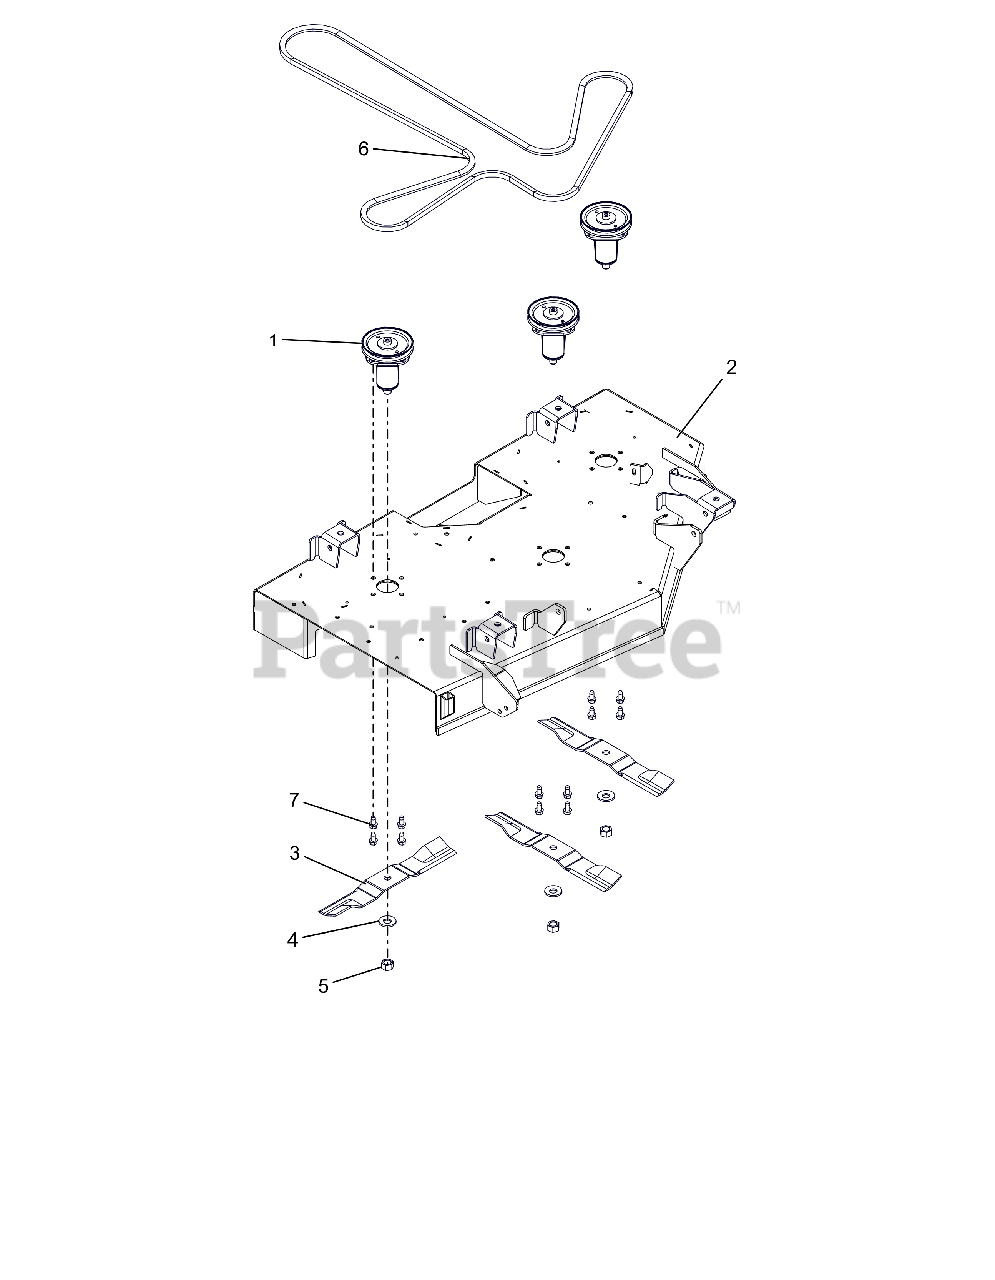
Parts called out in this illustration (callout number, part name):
1	KIT, DECK SPINDLE ASM-IKON-ZTX
2	KIT, 42" ARIENS DECK W/DECALS
3	BLADE, MOWER 15.00"
4	WSHR-BLVL .669X1.535X.138
5	NUT-HEX .62-18 YWZC
6	V-BELT, 4L-WRAPPED
7	@SCR-TAP .38-16X.75 HWH TR YWZ
